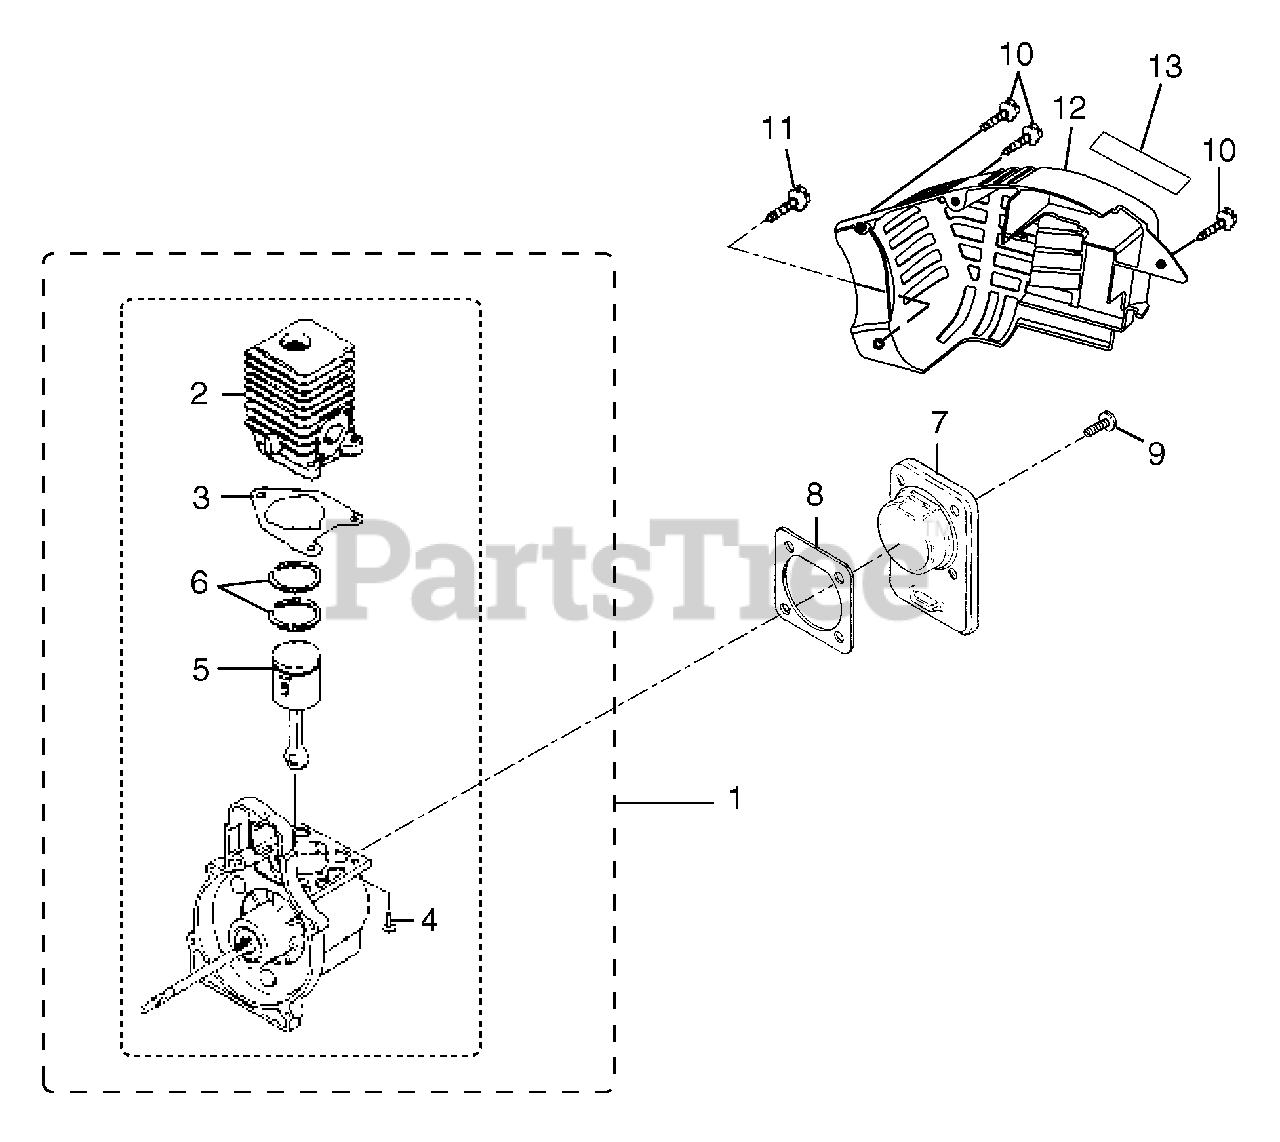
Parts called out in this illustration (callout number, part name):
1	SHORT BLOCK (30cc)
2	30cc CYLINDER
3	CYLINDER GASKET
4	SCREW (12-24 x 3/4 in. TOR x pan Hd.)
5	30cc PISTON ASSEMBLY
6	PISTON RING
7	CRANKCASE COVER
8	CRan KCASE GASKET
9	SCREW (10-24 x 9/16 in. pan Hd.)
10	SCREW (#8 x 1/2 in. pan Hd.)
11	SCREW (#10 x 3/4 in. TORx TRUSS Hd.)
13	ZIP START DECAL
